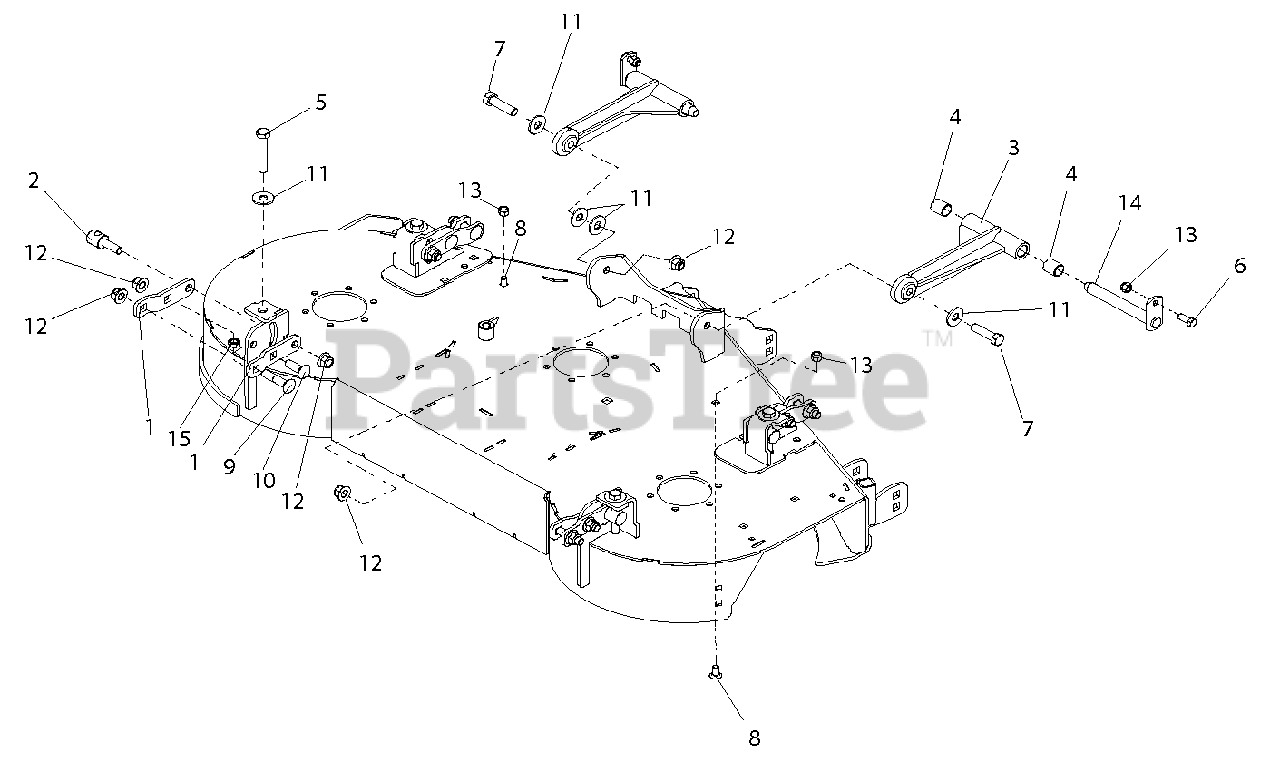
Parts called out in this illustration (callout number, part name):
1	BRKT, DECK LEVELING
2	TRUNNION, .50-13
3	WLDMT, DECK PUSHER ARM
4	BRG, .75 X .875 X 1.00
5	BLT-HEX .50-13 X 3.0 GR5 FTD YWZ
6	BLT-HEX .38-16 X 1.00 GR5 YWZC
7	BLT-HEX .50-13 X 2.00 GR5 YWZC
8	BLT-RHDSSQNK .38-16 X .75 G5YZ
9	BLT-RDHDSQNK .50-13 X 2.25 G5
10	BLT-RDHDSQNK .50-13 X 1.50 G5 YWZC
11	WSHR-FL-STL .563 X 1.38 X .109 YWZC
12	NUT-LK-NYL-FLG .50-13 YWZC
13	NUT-LK-NYL .38-16 YWZC
14	WLDMT, MOWER MTG PIN
15	NUT-JAM .50-13 YWZC
